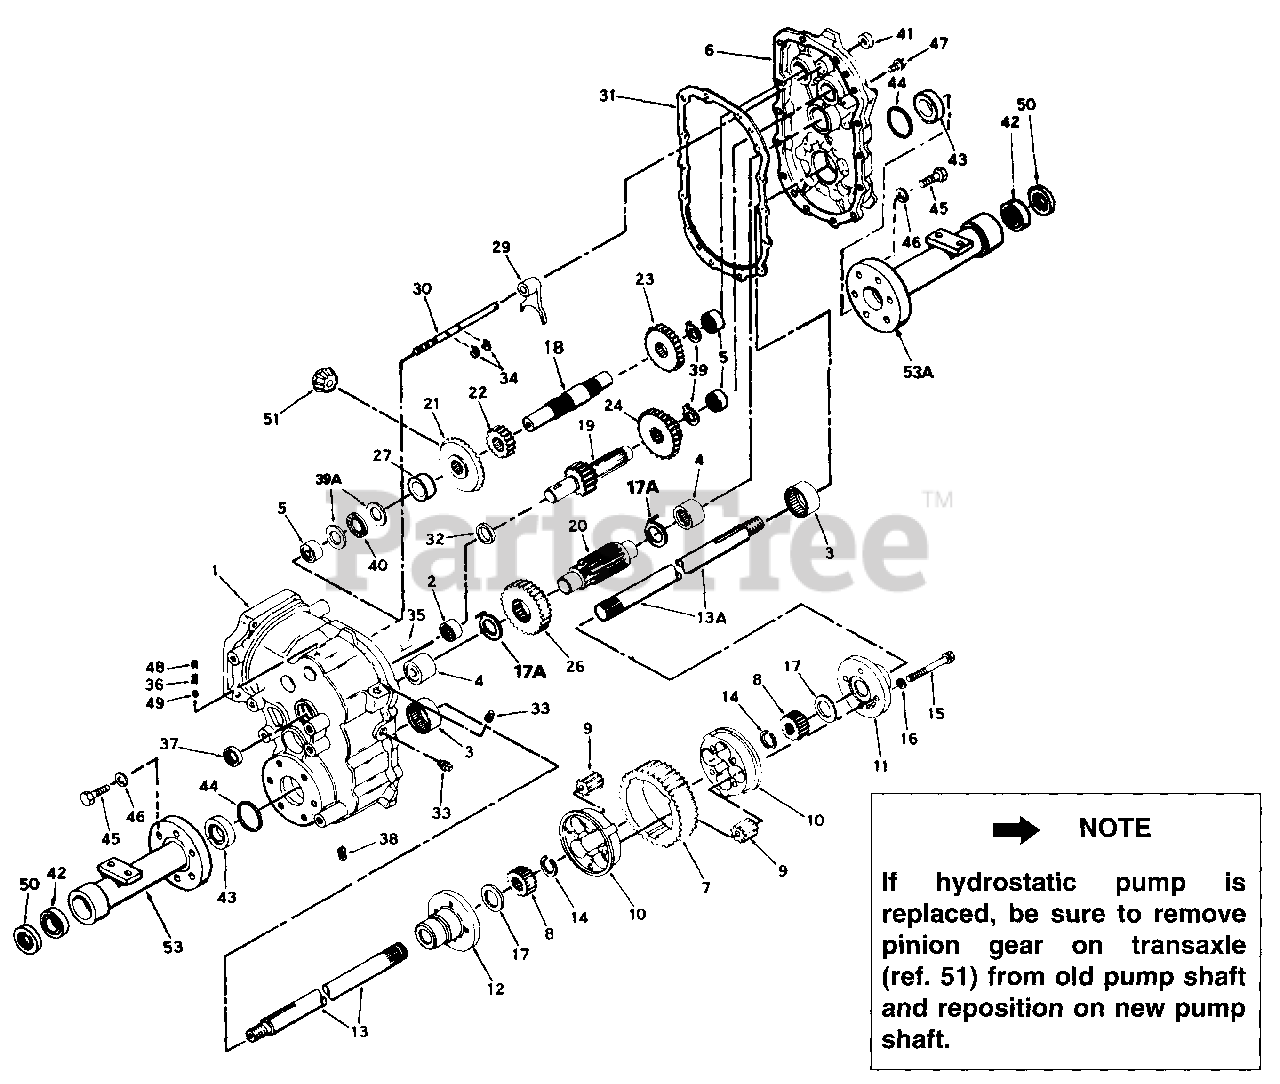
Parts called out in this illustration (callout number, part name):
1	Case Assembly, Transaxle
2	Bearing, Needle
3	Bearing, Needle
4	Bearing, Needle
5	Bearing, Needle
6	Cover Assembly, Transaxle
7	Gear, Ring
8	Gear, Side
9	Gear, Pinion
10	Core, Body
11	Carrier, Differential
12	Carrier, Differential
13	Axle, (18-17/64" Long)
13A	Axle, (15-29/64" Long)
14	Ring, Snap
15	Screw, Hex Hd. Mach.,3/8-16 x 3-3/8
16	Lock Washer, 3/8"
17	Washer, Thrust
17A	Washer, Thrust
18	Shaft, Counter
19	Shaft, Brake
20	Pinion, Output
21	Gear, Bevel (30 Teeth)
22	Gear, Spur (16 Teeth)
23	Gear, Spur (23 Teeth)
24	Gear, Cluster (20 and 27 Teeth)
26	Gear, Output (37 Teeth)
27	Spacer (55/64" Long)
29	Fork, Shift
30	Rod, Shift
31	Gasket, Case and Cover
32	Spacer
33	Plug, Pipe
34	Ring, Snap
35	Pin, Dowel
36	Spring
37	Seal, Oil
38	Plug, Magnetic Drain
39	Washer, Thrust
40	Bearing, Thrust
41	Seal, Oil
42	Bearing, Ball
43	Bearing, Thrust
44	Seal, Square Cut
45	Screw, Hex Hd. Mach.,1/2-13 x 1 1/2
46	Lock Washer, 1/2"
47	Screw, Hex Hd. Thd. 5/16-18 x 1
48	Screw, Set 1/4-20 x 1/2
49	Ball, Steel
50	Seal, Oil
51	Pinion, Bevel
53	Housing, Axle (9-1/4" Long)
53A	Housing, Axle
